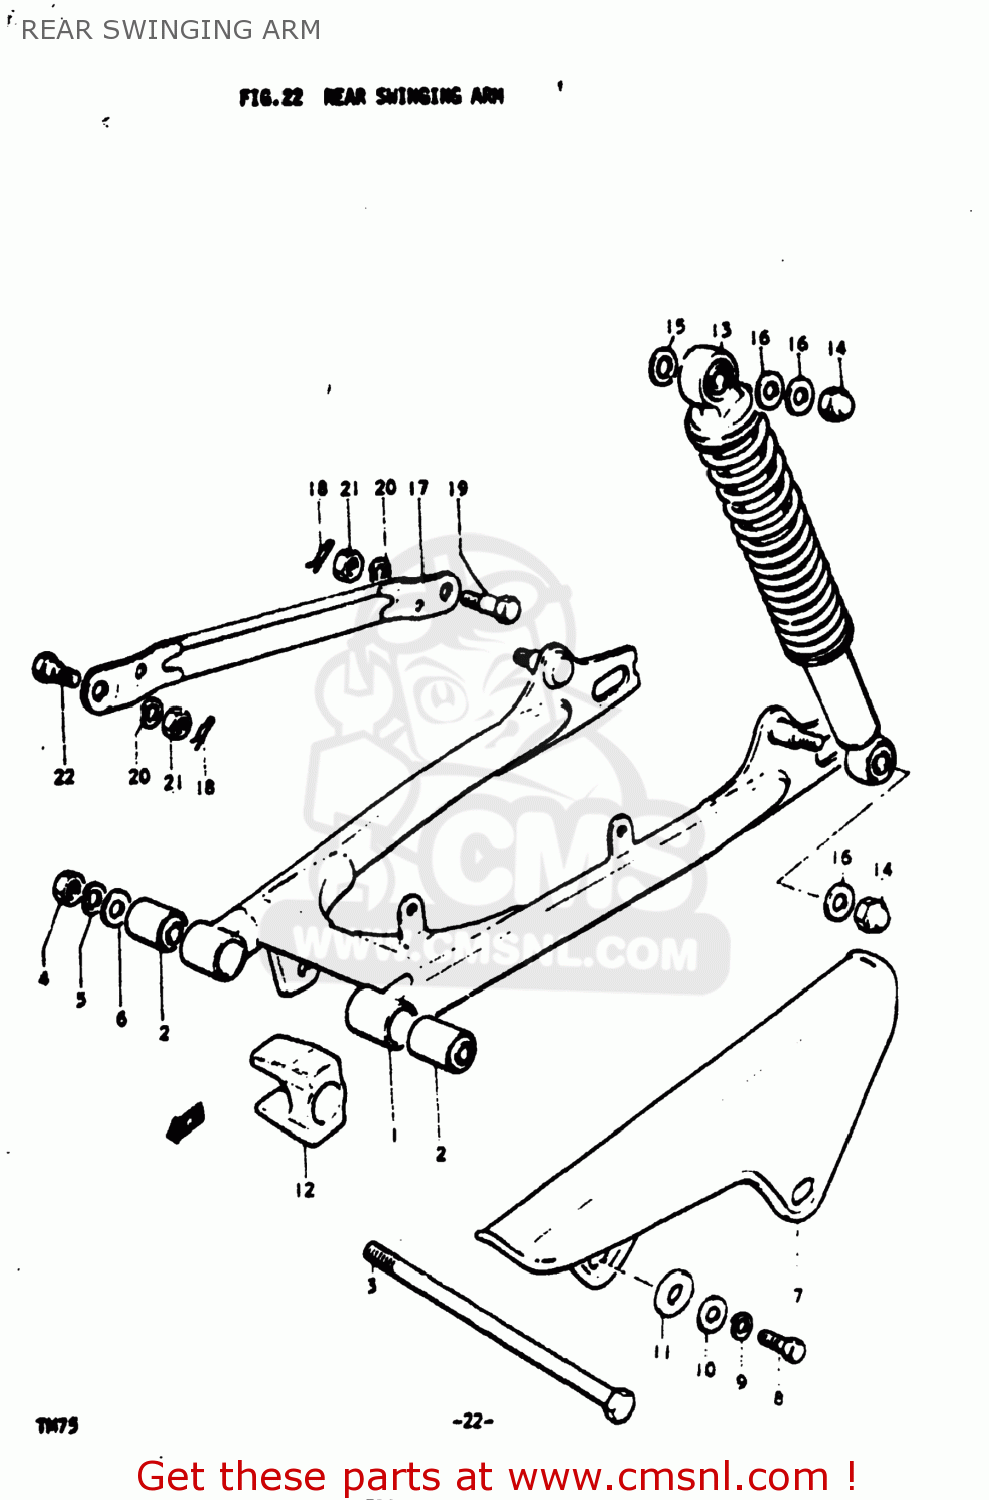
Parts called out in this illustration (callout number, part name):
1	SWING ARM ASSEMBLY,REAR
2	BUSHING(10X23X35)
3	SHAFT,RR SHOCK ABSORBER UPR
4	NUT
5	LOCK WASHER
6	WASHER
7	CASE,CHAIN
8	BOLT
9	LOCK WASHER
10	WASHER
11	WASHER
12	BUFFER,CHAIN TOUCH DEFLECTOR
13	ABSORBER ASSEMBLY,REAR SHOCK
14	NUT
15	WASHER
16	WASHER
17	TORQUE LINK,REAR
18	CLIP
19	BOLT(8X26.5)
20	LOCK WASHER
21	NUT
22	BOLT(8X22.5)
